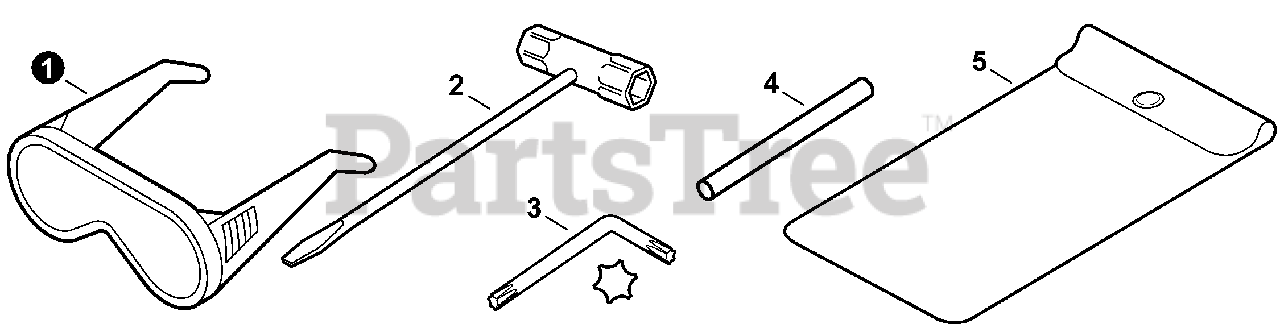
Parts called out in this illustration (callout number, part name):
1	GLASSES, SAFETY
2	T-WRENCH 17×19 L200
3	WRENCH, ALLEN T27 80×30
4	TOOL, LOCKING 5×120mm
5	BAG, TOOL
